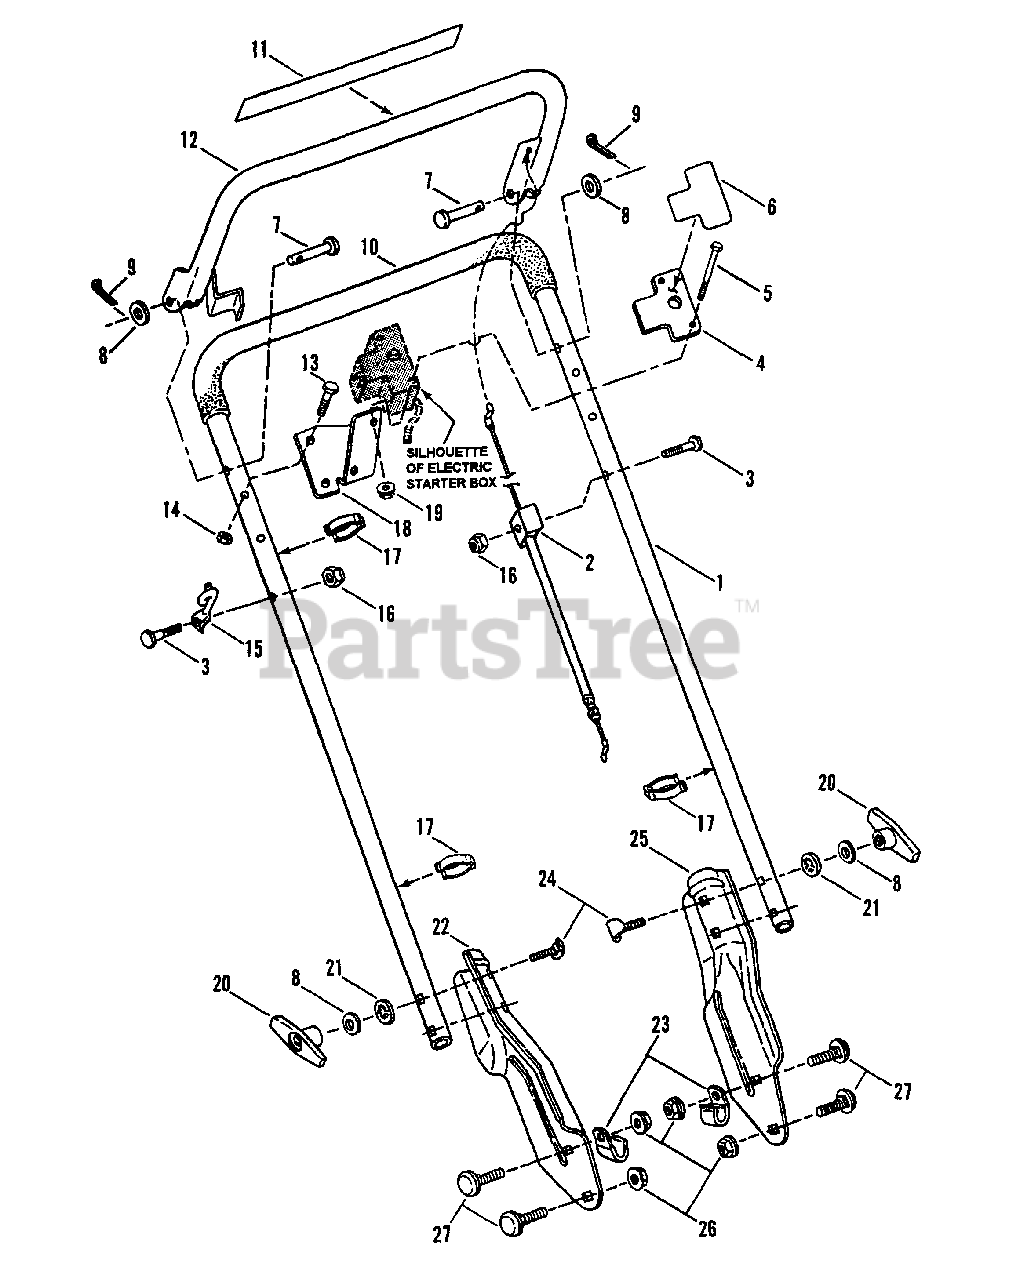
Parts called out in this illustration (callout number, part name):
1	HANDLE, Upper
2	CABLE, Blade Control
3	SCREW, 1/4-20 x 1 1/2 Hex Head Cap, Grade 5
4	COVER, Electric Starter
5	SCREW, #8-32 x 2 1/2" Hex Head Cap
6	DECAL, Electric Starter
7	PIN, 5/16 x 1.43" Clevis
8	WASHER, 5/16 Flat
9	COTTER-PIN, 3/32 x 1/2
10	GRIP, Foam (Yellow)
11	DECAL, Blade Control
12	CONTROL, Blade (Yellow)
13	BOLT, #10-24 x 1 1/4 Hex Head, Grade 5
14	NUT, #10-24 Hex Lock
15	GUIDE, Rope
16	NUT, 1/4-20 Hex Nyloc
17	CLIP, Wiring Harness
18	BRACKET, Electric Starter
19	NUT, #6-32 Hex (KEPS)
20	KNOB, 5/16-18 Thread
21	WASHER, 5/16 Internal Tooth Lock
22	BRACKET, Handle (Right Side)
23	CLIP, Vinyl Covered
24	SCREW, 5/16-18 x 2" Curved Head, Grade 2
25	BRACKET, Handle (Left Side)
26	NUT, 5/16-18 Hex Flange Lock, Grade 5
27	BOLT, 5/16-18 x 5/8 Short Neck Carriage
